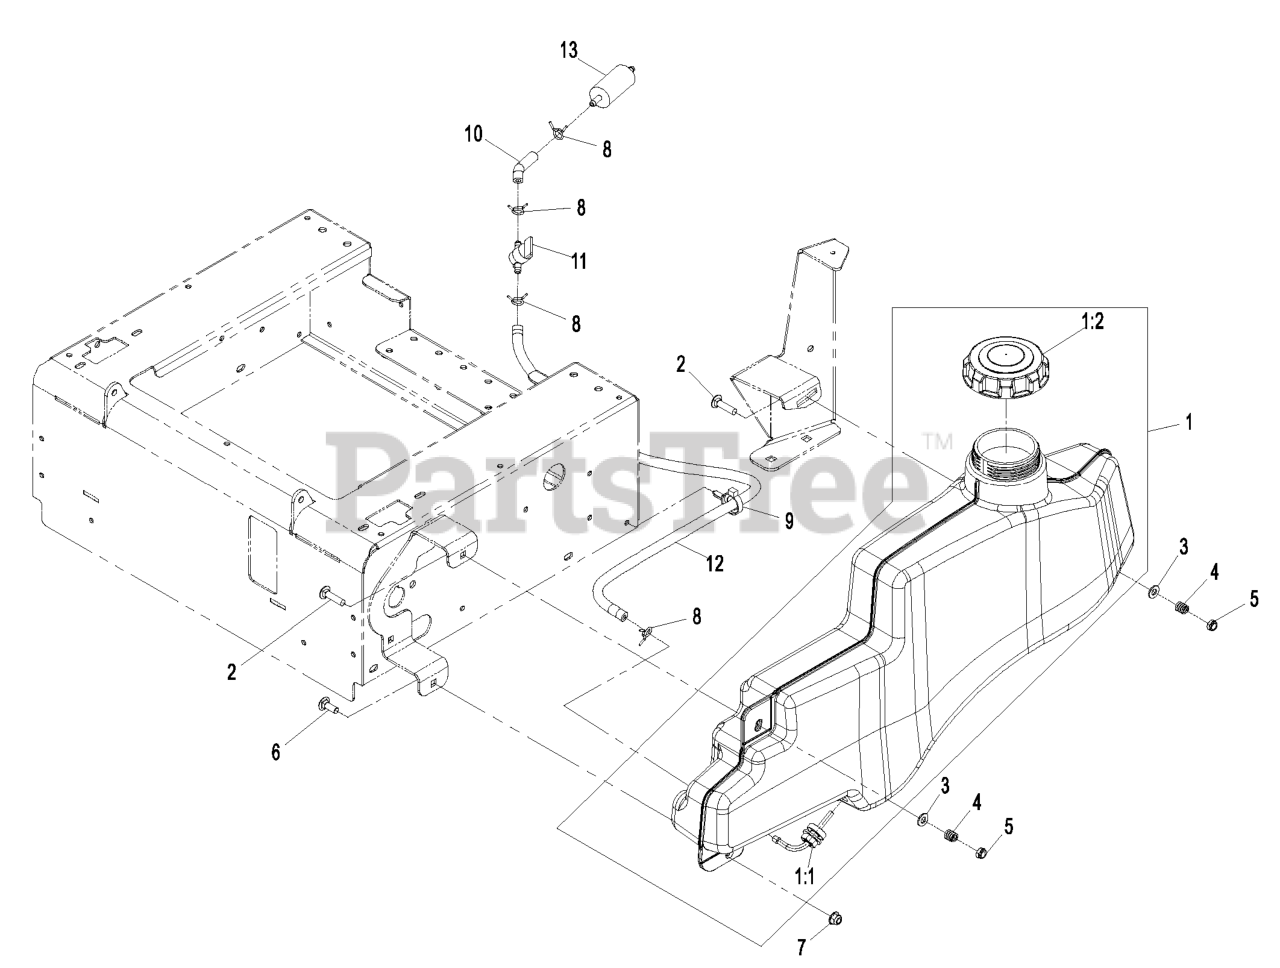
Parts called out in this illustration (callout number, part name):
1	FUEL TANK ASM
1:1	FITTING-FUEL, BULKHEAD
1:2	CAP-FUEL, GAS
2	Bolt-Carriage 5/16-18 X 1 1/4
3	WASHER-PLAIN
4	SPRING-TANK, FUEL
5	NUT-LOCK, NI
6	SCREW-CARR
7	NUT-HF, NI
9	CLAMP-HOSE
10	HOSE-FUEL
11	VALVE-FUEL
12	HOSE-FUEL
13	Part No. 695666 Fuel Filter
